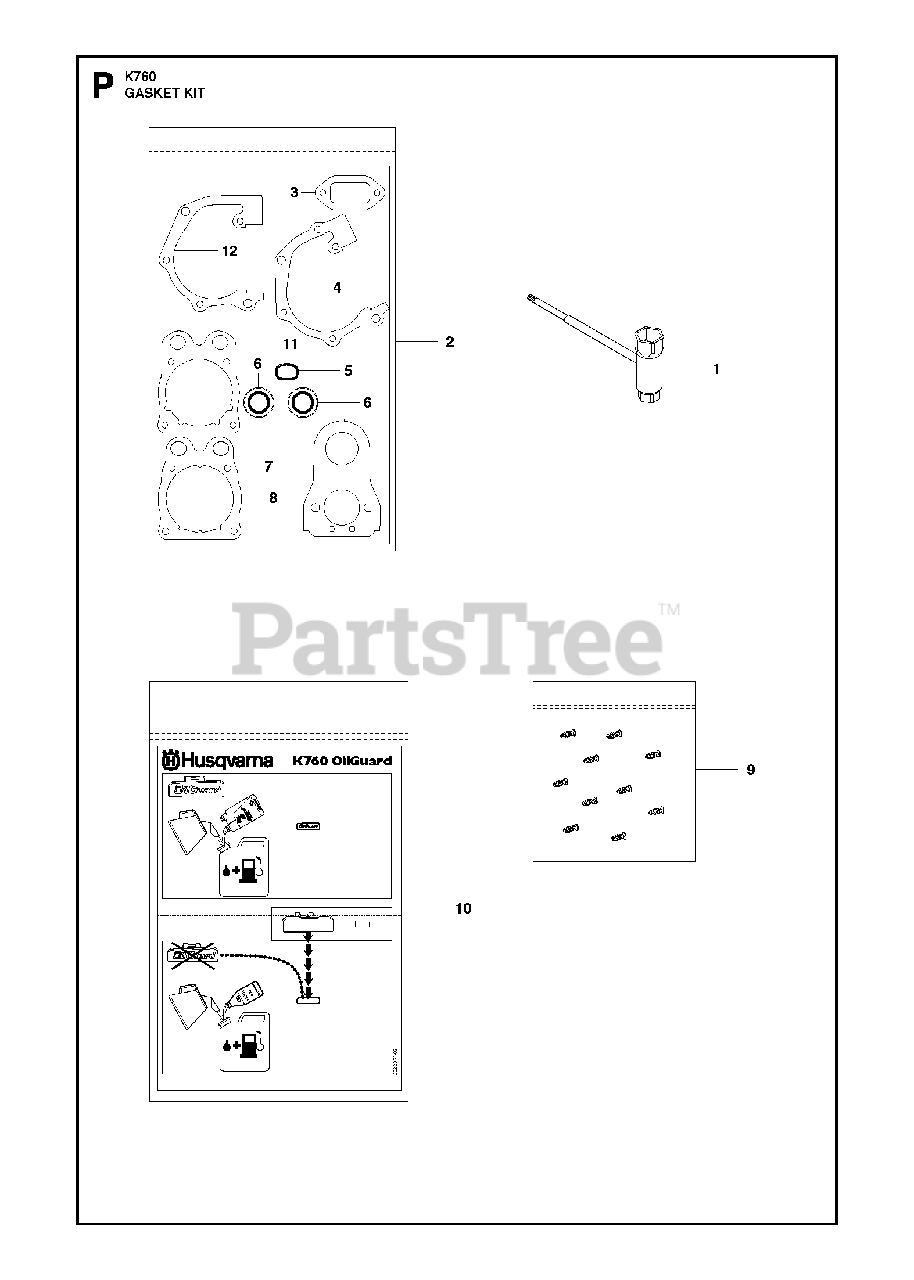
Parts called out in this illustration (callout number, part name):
2	GASKET KITIncl. 3-8, 11-12
3	GASKET
6	SEALING RINGBlue
9	KITIncl. 10 Pins
